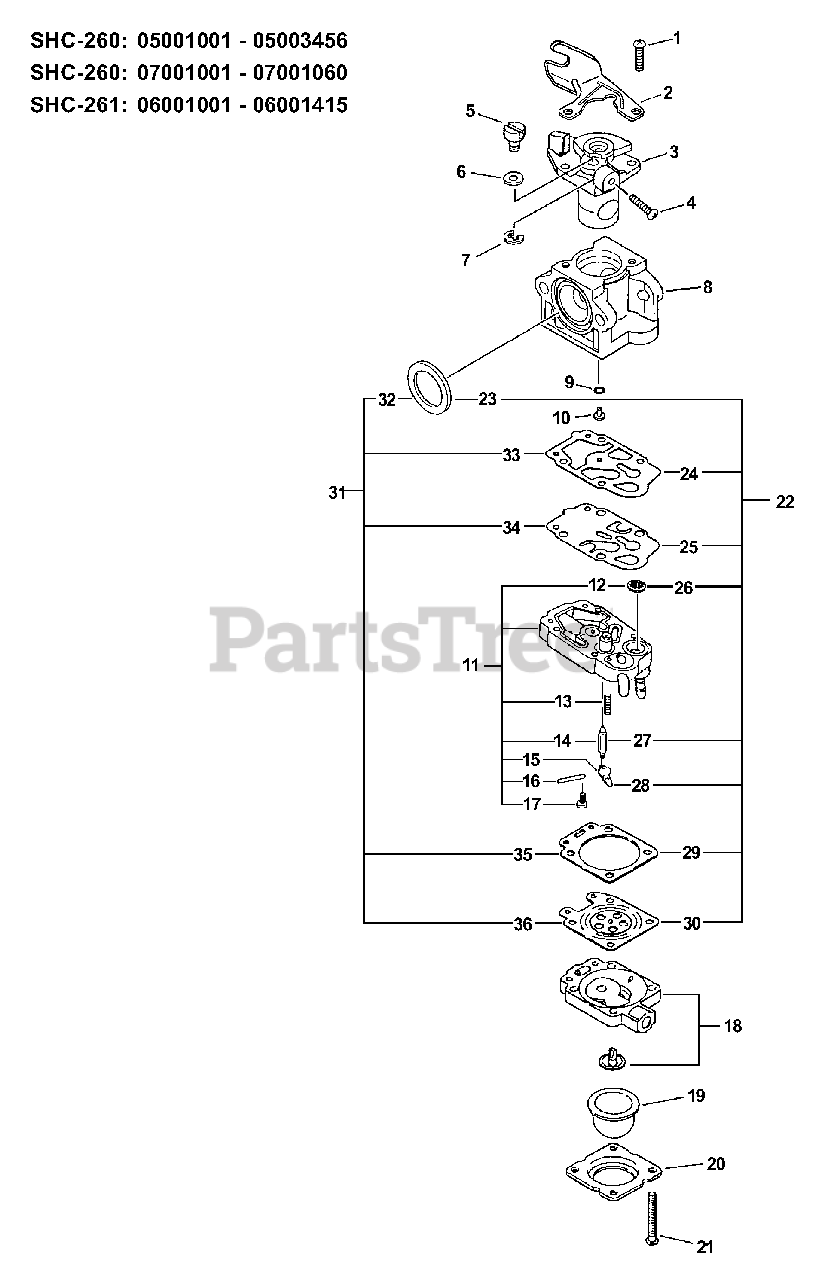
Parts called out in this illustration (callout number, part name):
2	BRACKET, THROTTLE CABLE
3	THROTTLE VALVE ASSY
8	BODY, CARBURETOR
10	JET, MAIN
11	BODY ASSY, PUMP
12	STRAINER
13	SPRING, METERING LEVER
14	VALVE, INLET NEEDLE
15	LEVER, METERING
16	PIN, METERING LEVER
18	BODY ASSY, PURGE
19	BULB, PURGE
20	RETAINER, PURGE BULB
22	REPAIR KIT, CARBURETOR
23	SEAL
24	GASKET, PUMP
25	DIAPHRAGM, PUMP
26	STRAINER
27	VALVE, INLET NEEDLE
28	LEVER, METERING
29	GASKET, METERING
30	DIAPHRAGM, METERING
31	GASKET / DIAPHRAGM KIT
32	SEAL
33	GASKET, PUMP
34	DIAPHRAGM, PUMP
35	GASKET, METERING
36	DIAPHRAGM, METERING
